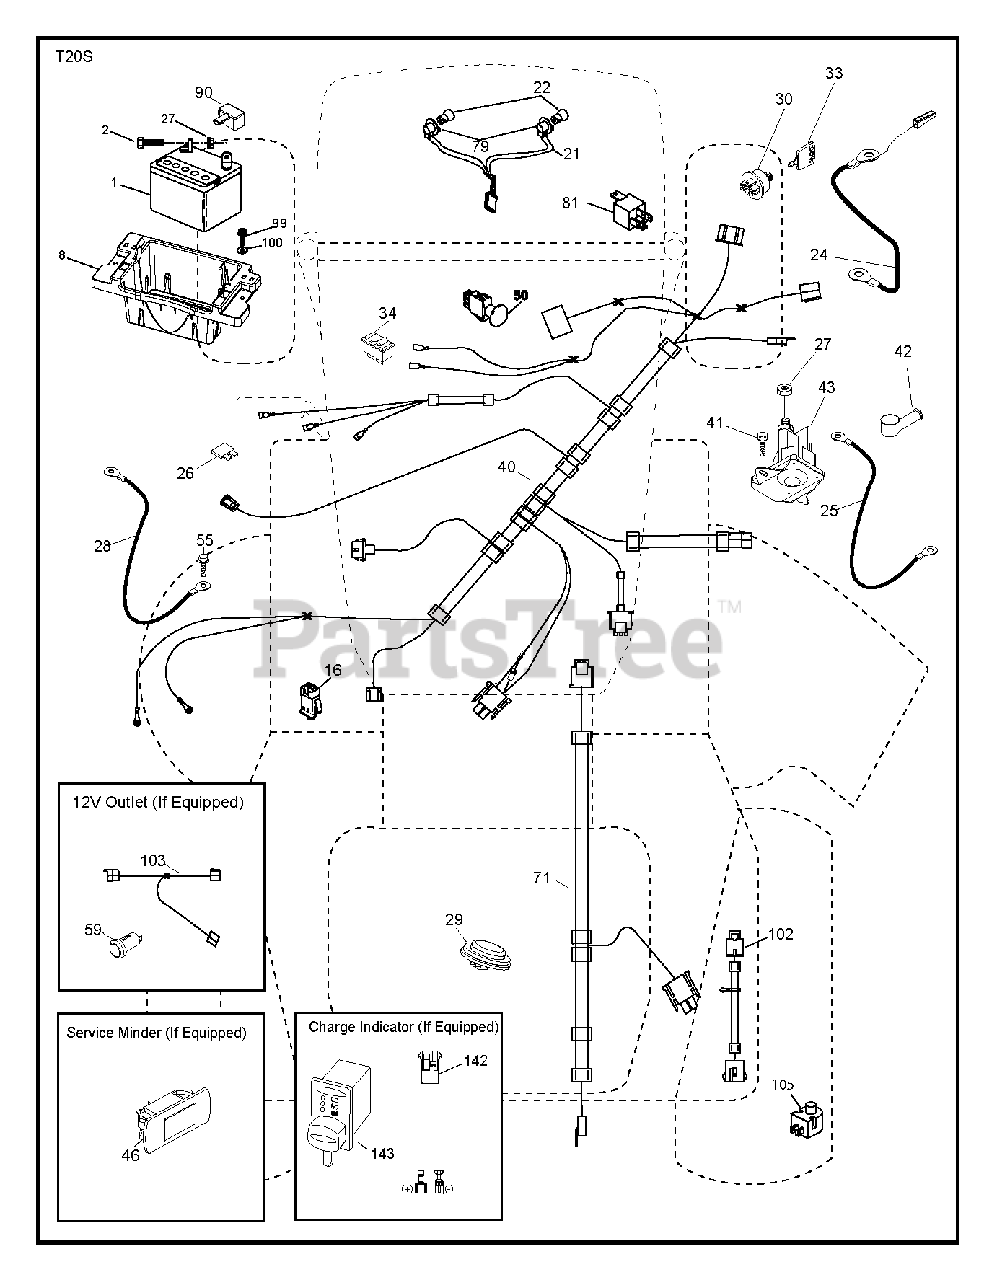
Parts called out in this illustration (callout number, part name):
1	Battery, Dry 30 Amp
2	BOLT.HEX.1/4.X.3/4.DICHROMATE
8	TRAY.BATTERY BOX.FRONT
16	SWITCH INTERLOOK PUSH-IN
21	HARNESS.LIGHT W/4152J BULBS
24	CABLE.FRBATT.W/WIRE.8GA.8
25	CABLE.STARTER.8GA.17.5
26	FUSE 20AMP
27	NUT
28	CABLE.GROUND.21"BLK.8GA.90T
29	SWITCH.SEAT.DELTA.OPC.
30	SWITCH.IGN.DELTA.W.LGH.ROS
33	KEY.CHAIN.BLISTER.PACK.GEN.USA
40	HARNESS.IGN.ELEC.RELAY.TEX.46
41	SCREW
42	TERMINAL COVER
43	SOLENOID.STARTER.BRASS.PLUNGER
46	GUAGE.SRVCMNDR.HRMTR.
50	SWITCH.PTO.8TERMINAL.STD.BLK
55	SCREW 5/16"
71	HARNESS-CHASSIS SUB
79	BULB HOLDER ASM.
81	RELAY HARNESS.SEALED
90	COVER.TERMINAL.BATTERY
99	SCREW HEXWSHR 1/4-20X3/4
102	REVERSE SWITCH
105	HARNESS PIGTAIL PCH TEX ROS
